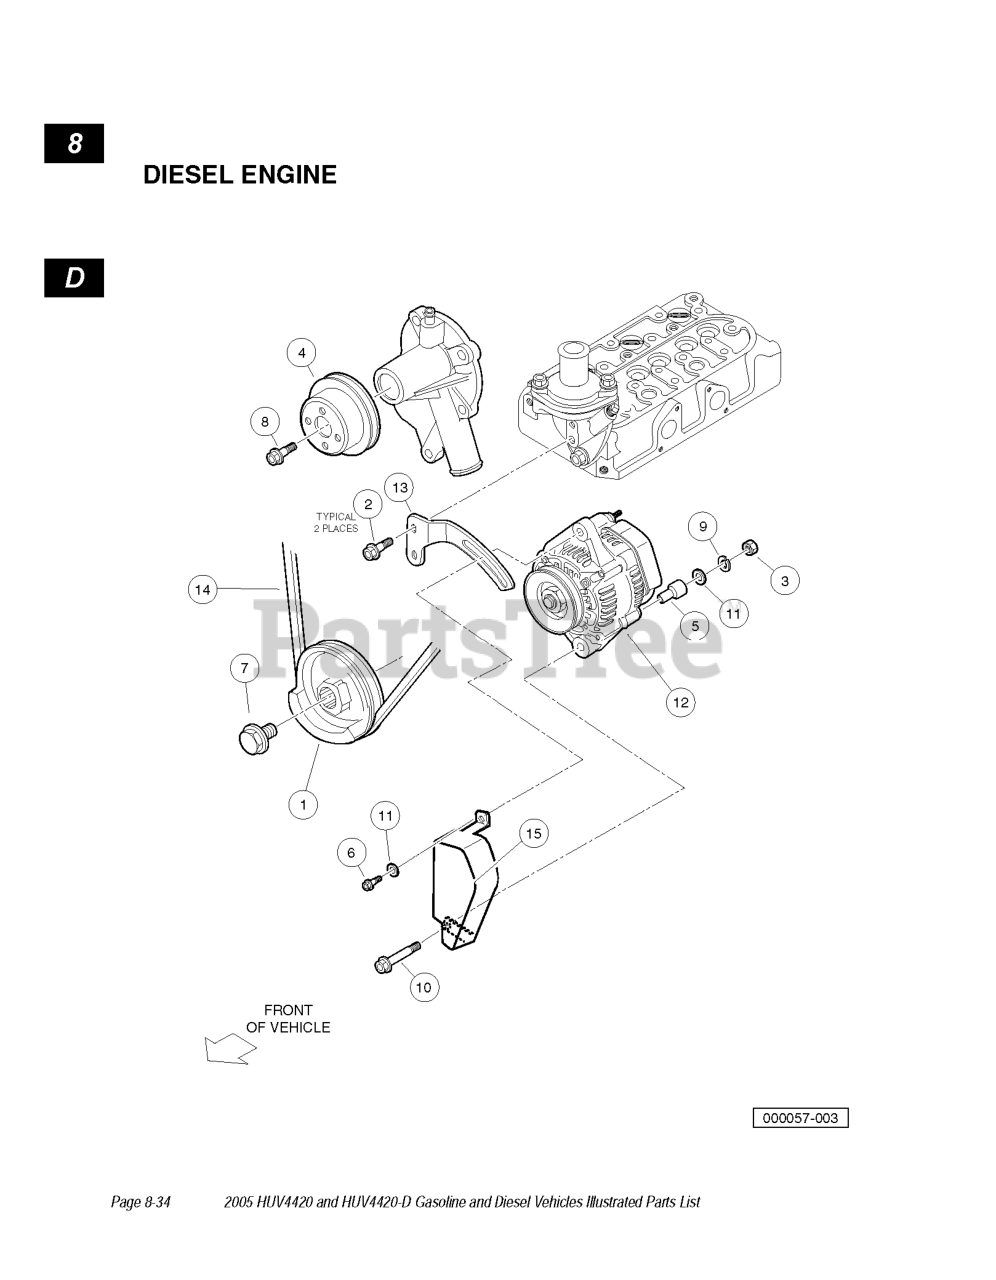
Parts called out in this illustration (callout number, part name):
1	PULLEY, FAN DRIVE
2	BOLT, M6X1X20
3	NUT-ALT-LOWER
4	PULLEY, WATER PUMP
5	COLLAR, ALTERNATOR ASSY, D722
6	BOLT, ALT, D722, ADJUSTER
7	BOLT, ALT, D722, DRIVE PULLEY
8	BOLT, D722, DRIVE PULLEY
9	WASHER-ALT-LOCK
10	BOLT-ALT-LOWER
11	WASHER-ALT-UPPER
12	ALTERNATOR, 60 AMP
